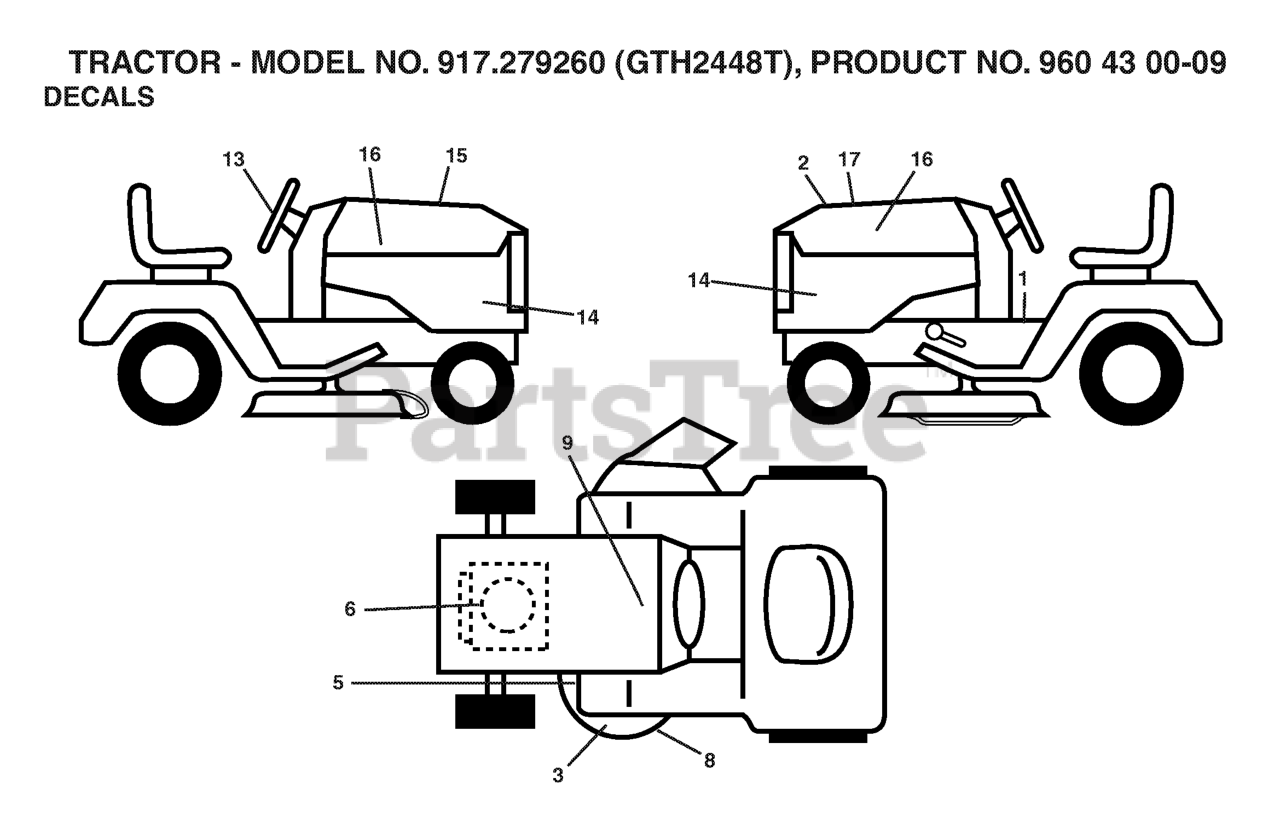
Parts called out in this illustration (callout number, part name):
2	DECAL.HOOD.TOP.INSERT.
3	DECAL.WARN.KEEP.HAND.AWAY
5	DECAL CLUTCH/BRAKE
8	DECAL.MOWER.SCH.48/54
9	DECAL BTRY SYMBOLS
13	DECAL.WHEEL.STRG.LGN.H
15	DECAL HOOD CUST. RESP.
16	DECAL.HOOD.NAMELOGO.HUSQ
